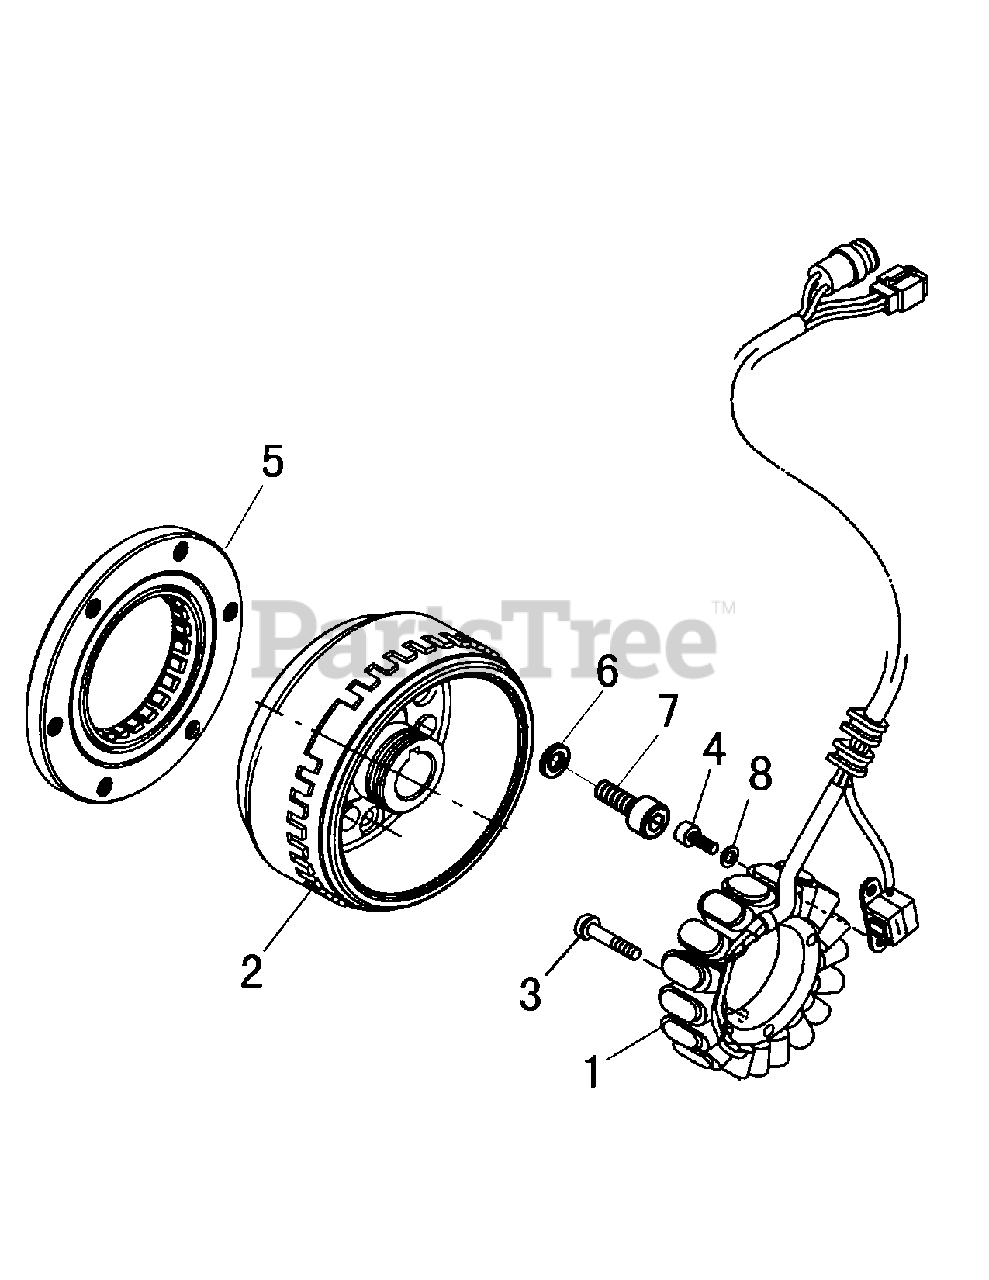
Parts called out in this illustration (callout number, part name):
1	Stator-Comp
2	Rotor-Comp
3	Flange Bolt M6X30
4	Screw-Hex Head M5
5	One Way Starter-Co
7	Screw-Hex Head M8
